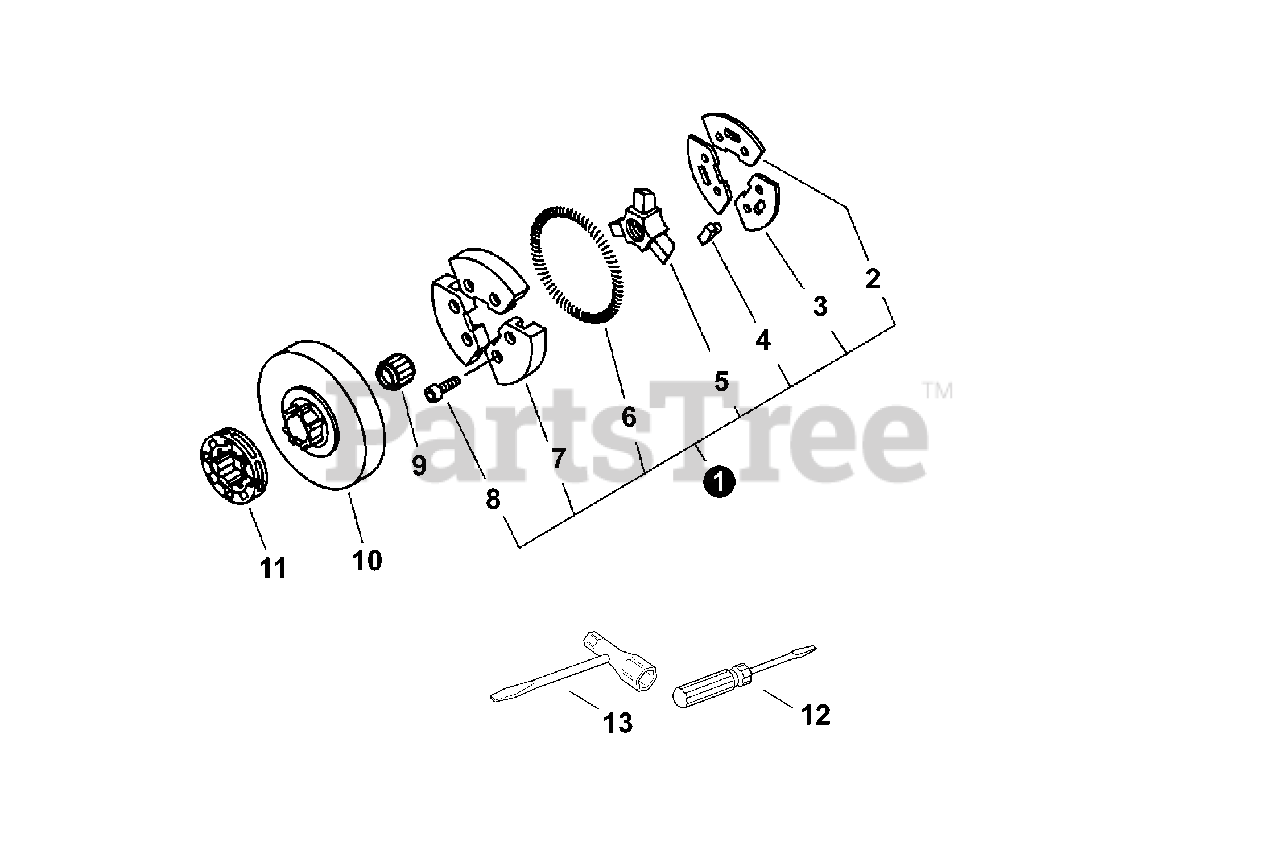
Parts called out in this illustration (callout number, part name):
1	CLUTCH ASY
2	PLATE, CLUTCH
3	PLATE, CLUTCH
4	PLATE, SPRING
5	HUB, CLUTCH
6	SPRING, CLUTCH
7	CLUTCH SHOE SET
8	BOLT 4×8
9	BEARING, NEEDLE
10	DRUM, CLUTCH
11	SPROCKET, RIM 682100
12	SCREWDRIVER
13	WRENCH W/SCREWDRIVER
